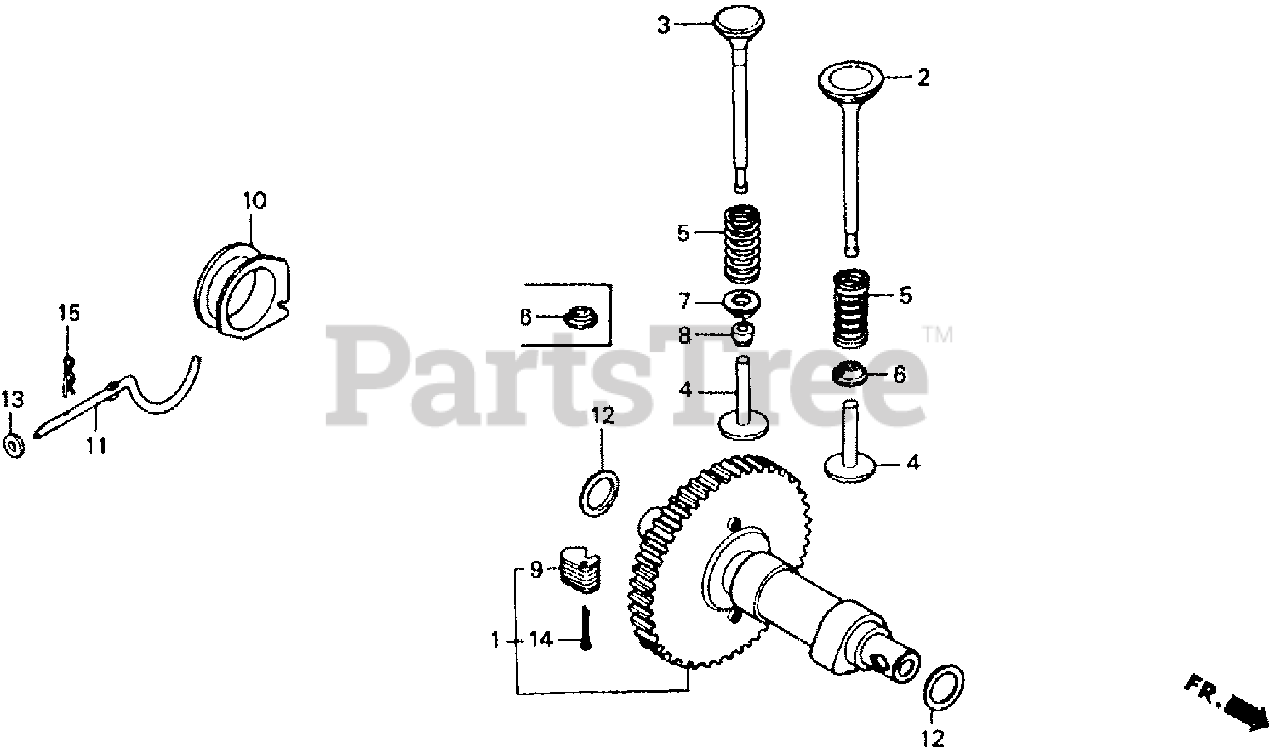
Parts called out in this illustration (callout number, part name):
1	CAMSHAFT ASSY.
2	VALVE, IN.
3	VALVE, EX.
4	LIFTER, VALVE (45.89MM)
4	LIFTER, VALVE (46.04MM)
4	LIFTER, VALVE (46.19MM)
4	LIFTER, VALVE (46.34MM)
5	SPRING, VALVE
6	RETAINER, VALVE SPRING
7	RETAINER, VALVE SPRING
8	ROTATOR, EX. VALVE
9	WEIGHT, GOVERNOR
10	SLIDER, GOVERNOR
11	SHAFT, GOVERNOR
12	WASHER, THRUST (18MM)
13	WASHER, PLAIN (6MM)
14	PIN, COTTER (3.0X45)
15	PIN, LOCK (10MM)
